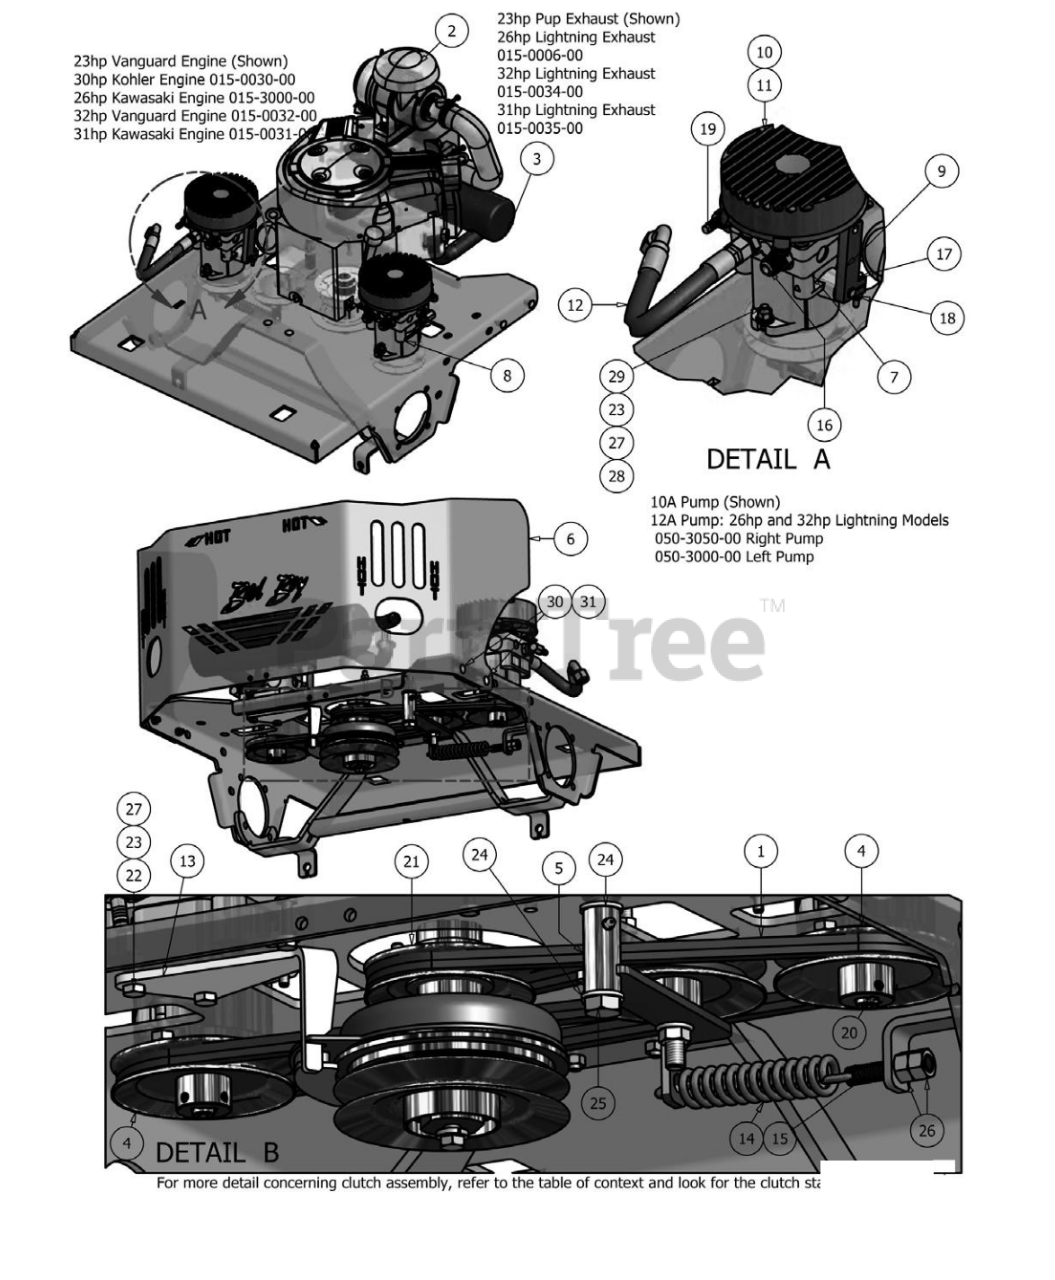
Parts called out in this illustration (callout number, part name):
2	23 HP Vanguard Motor
3	23 HP Vanguard Exhaust
4	5" Pump Pulley
5	Pump Idler Bracket
6	Pup Rear Plate
7	Right Hydraulic Pump
8	Left Hydraulic Pump
9	Pup Pump Arm
10	Hydraulic Fan
12	Hydraulic Hose
13	PTO Engager Holder
14	Pump Idler Spring 6"
15	Spring Tensioner
16	Hydraulic Fitting
17	1/4" x 1 1/2" Bolt
18	1/4" Nylock Nut
19	3/8" X 9/16" Male Fitting
20	5mm x 1" Key
21	4 3/4" Motor Pulley
22	3/8" x 1" Hex Bolt
23	3/8" Hex Nut
24	.635 ID Plastic Washer
25	5/8" x 4" Hex Bolt
26	1/2" Hex Nut
27	3/8" Lock Washer
28	3/8" Flat Washer
29	3/8" x 1 1/2" Hex Bolt
30	5/16" x 1" Carriage Bolt
31	5/16" Nylock Nut
32	Canister Filter (23 Pup only)
33	Outer Canister Air Filter (26hp & 32hp Lightning and 30hp Pup)
34	Inner Canister Air Filter (26hp & 32hp Lightning and 30hp Pup)
